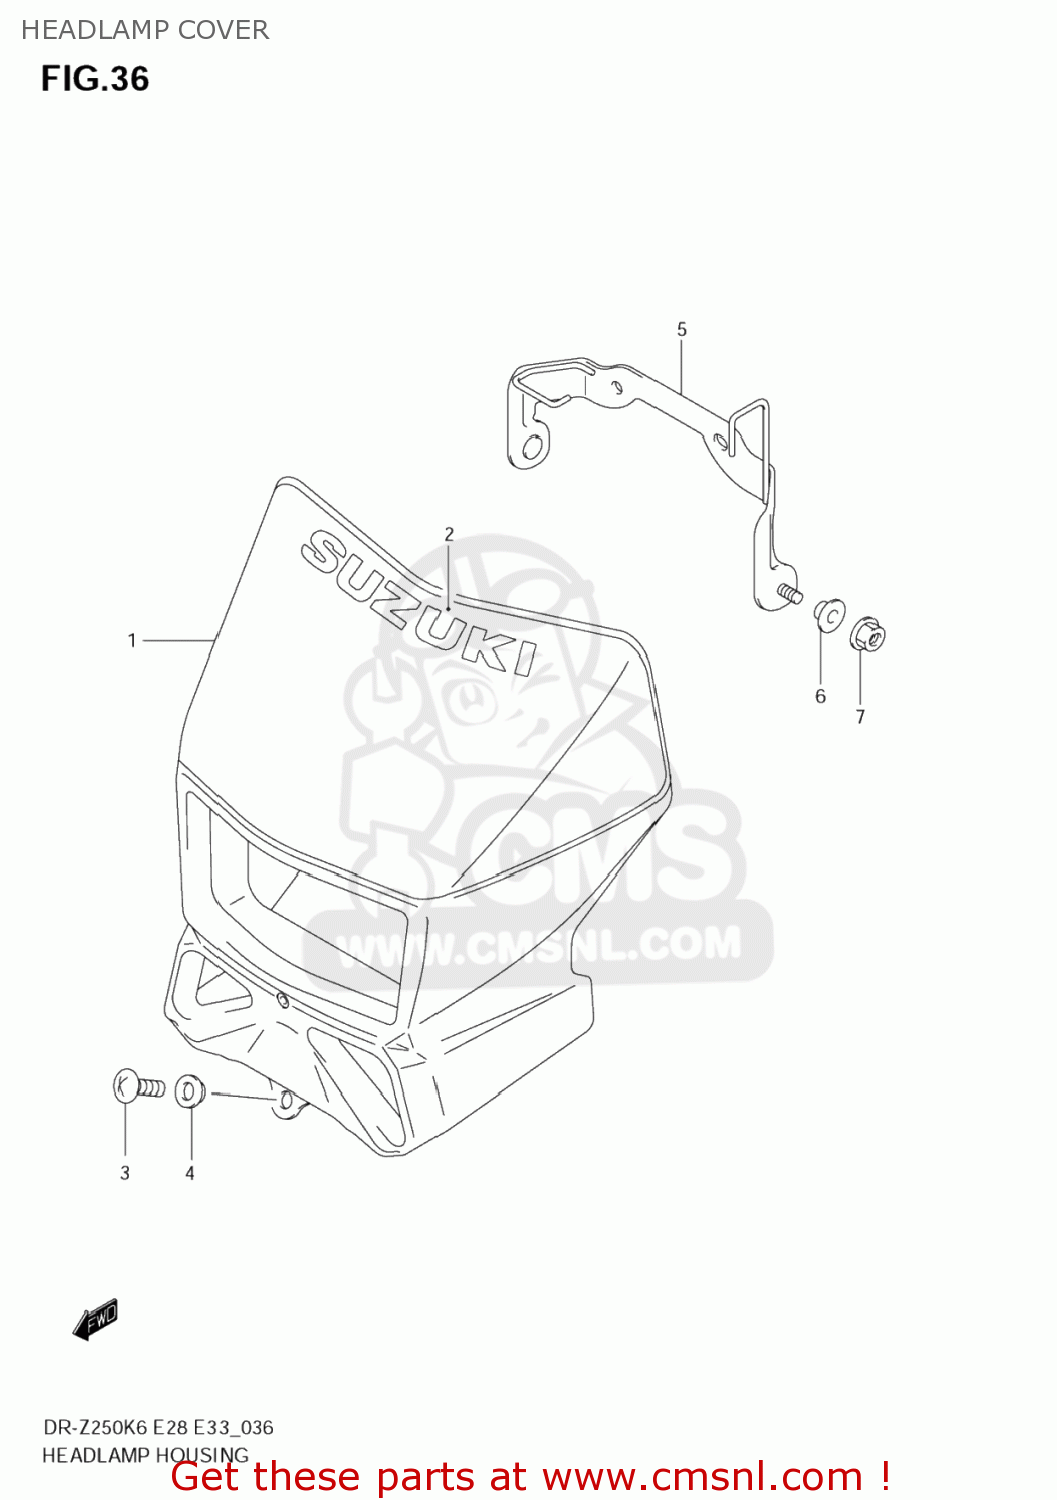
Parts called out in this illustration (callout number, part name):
1	COVER,HEADLAMP(YELLOW)
2	TAPE,HEADLAMP HOUSING
3	SCREW(5X12)
4	WASHER
5	BRACKET,HEADLAMP COVER
6	WASHER
7	NUT
